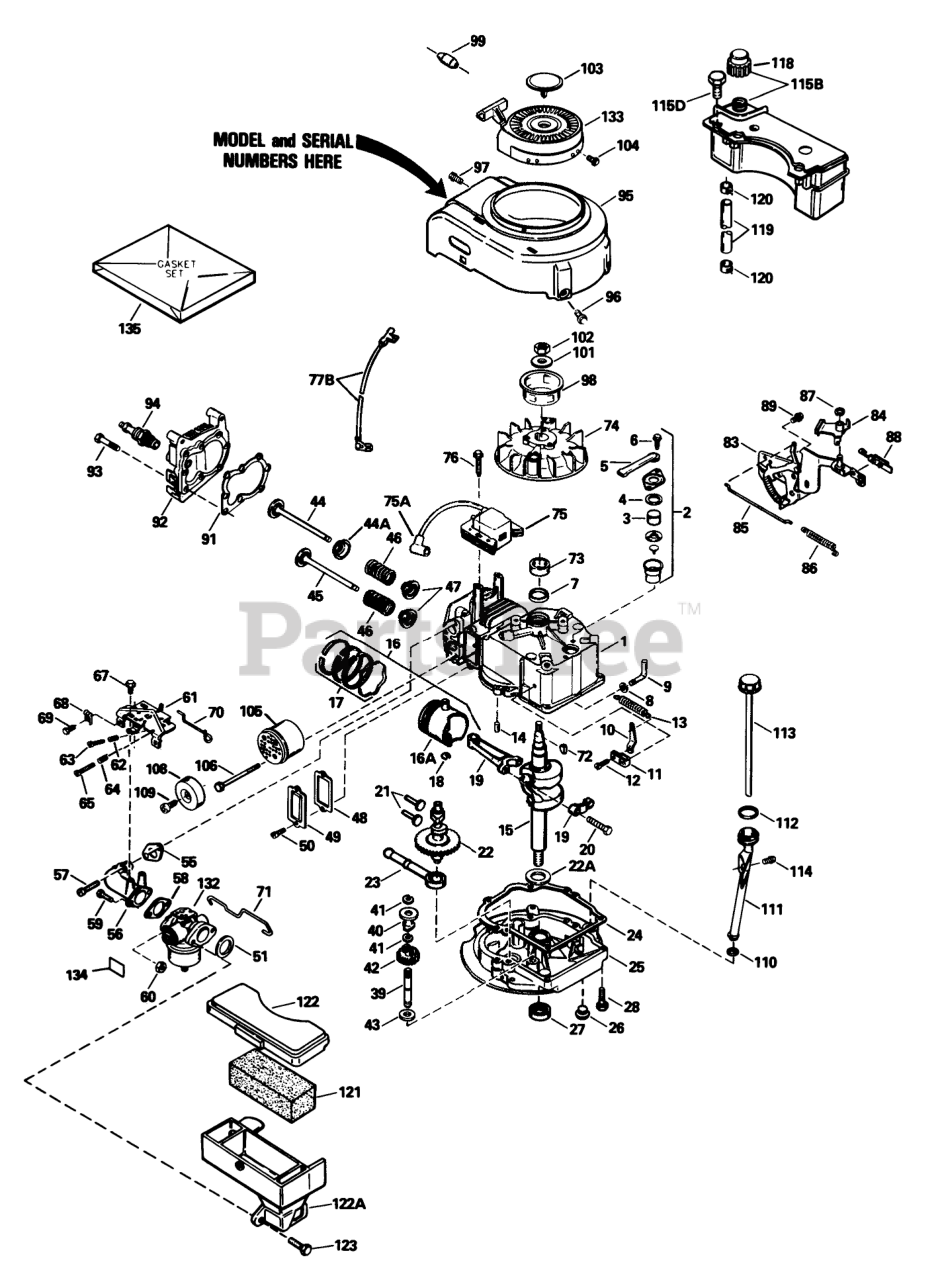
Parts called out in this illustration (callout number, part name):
1	Cylinder Assembly (Incl. Ref. #7 & 14)
2	Breather Assembly (Incl. Ref. #3-6)
3	Element-Breather
4	Gasket-Breather
5	Tube, Breaker
6	Screw (10-24 x 9/16)
7	Seal-Oil
8	Washer-Flat
9	Rod-Governor (Incl. Ref. #8)
10	Governor Lever
11	Clamp-Lever, Governor
12	Screw
13	Spring Governor
14	Pin-Dowel
15	Crankshaft
16	Piston-Pin & Ring Assy. (Std.)(Incl. Ref. #16A, 17 & 18)
16	Piston-Pin & Ring Assembly (.010 oversize)(Incl. Ref. #16A, 17 & 18)
16	Piston-Pin & Ring Assembly (.020 oversize)(Incl. Ref. #16A, 17 & 18)
16A	Piston & Pin Assembly (Std.)(Incl. Ref. #18)
16A	Piston & Pin Assembly (.010 oversize)(Incl. Ref. #18)
16A	Piston & Pin Assembly (.020 oversize)(Incl. Ref. #18)
17	Ring Set-Piston (Std.)
17	Ring Set, Piston(.0100versize)
17	Ring Set (.020" OS)
18	Ring-Retaining, Piston Pin
19	Rod Assembly-Connecting (Incl. Ref. #20)
20	Bolt-Rod, Connecting
21	Lifter-Valve
22	Camshaft(Mech.Comp. Release)
22A	Washer-Thrust
23	Oil Pump ASM
24	Gasket
25	Flange-Mounting (Incl. Ref. #26, 27 & 39)
26	Plug Oil Drain
27	Seal-Oil
28	Screw (1/4-20 x 1-1/4)
39	Shaft-Governor
40	Spool-Governor
41	Ring-Retaining
42	Gear Assembly-Governor (Incl. Ref. #43)
43	Washer
44	Valve-Intake (Std.)(Incl. Ref. #47)
44	Valve-Intake (1 /32" oversize)(Incl. Ref. #47)
44A	Seal Assy., Intake
45	Valve-Exhaust (Std.)(Incl. Ref. #47)
45	Valve-Exhaust (1 /32" oversize) (Incl. Ref. #47)
46	Spring-Valve
47	Cap-Valve, Spring
48	Gasket-Cover, Valve
49	Cover-Valve
51	Gasket-Cleaner, Air
55	Gasket-Intake Pipe
56	Pipe-Intake (Incl. Ref. #55)
57	Screw (1/4-20 x 1)
59	Screw (1/4-28 x 7/8)
60	Nut and Lock Washer (1/4-28)
61	Bracket Assembly-Control (Incl. Ref. #62-65)
62	61709/GIL1515A/95-5
63	Screw
64	Spring-Compression
65	Screw
67	Screw (10-24 x 9/16)
68	Conduit
69	Screw (10-32 x 3/8)
70	2035A67 ADD.ASSEMBL
71	Link-Throttle
72	Key-Flywheel
74	Flywheel
75	Solid State
75A	Cover-Spark Plug
76	Screw
77B	Ground Wire
83	Bracket-S.E. Brake
84	Lever-Brake
85	Link-Control
86	Spring-Extension
87	Ring-Retaining
88	Terminal
89	Screw (1/4-20 x 3/8)
91	Gasket-Cylinder Head
92	Head-Cylinder
93	Screw (5/16-18x1-1/2)
94	Spark Plug-Resistor (R J19 L M)
95	Housing-Blower
96	Screw (1/4-20 x 1/2)
97	Screw (10-24 x 9/16)
98	Hub-Starter
99	Retainer-Starter Rope
101	Washer-Belleville
102	Nut-Flywheel
103	Plug Starter
104	Screw, Hex Hd.
105	Muffler Assembly (Incl. Ref. #106)
108	Cover-Muffler
109	Screw (8-32 x 3/8)
111	Oil Fill Tube
113	Dipstick
114	Screw (10-32 x 1/2)
115B	Tank Assembly (Incl. Ref. #118 & 126)
115D	Screw (10-32 x 35/64)
118	Cap-Fuel
119	Line-Fuel
120	Clamp-Line, Fuel
121	Filter-Air Cleaner
122	Cover Air Cleaner
122A	Body Air cleaner
132	Carburetor (Incl. Ref. #58)
133	Starter-Rewind
134	Decal-Primer
135	Gasket Set (Incl. Items Marked )
